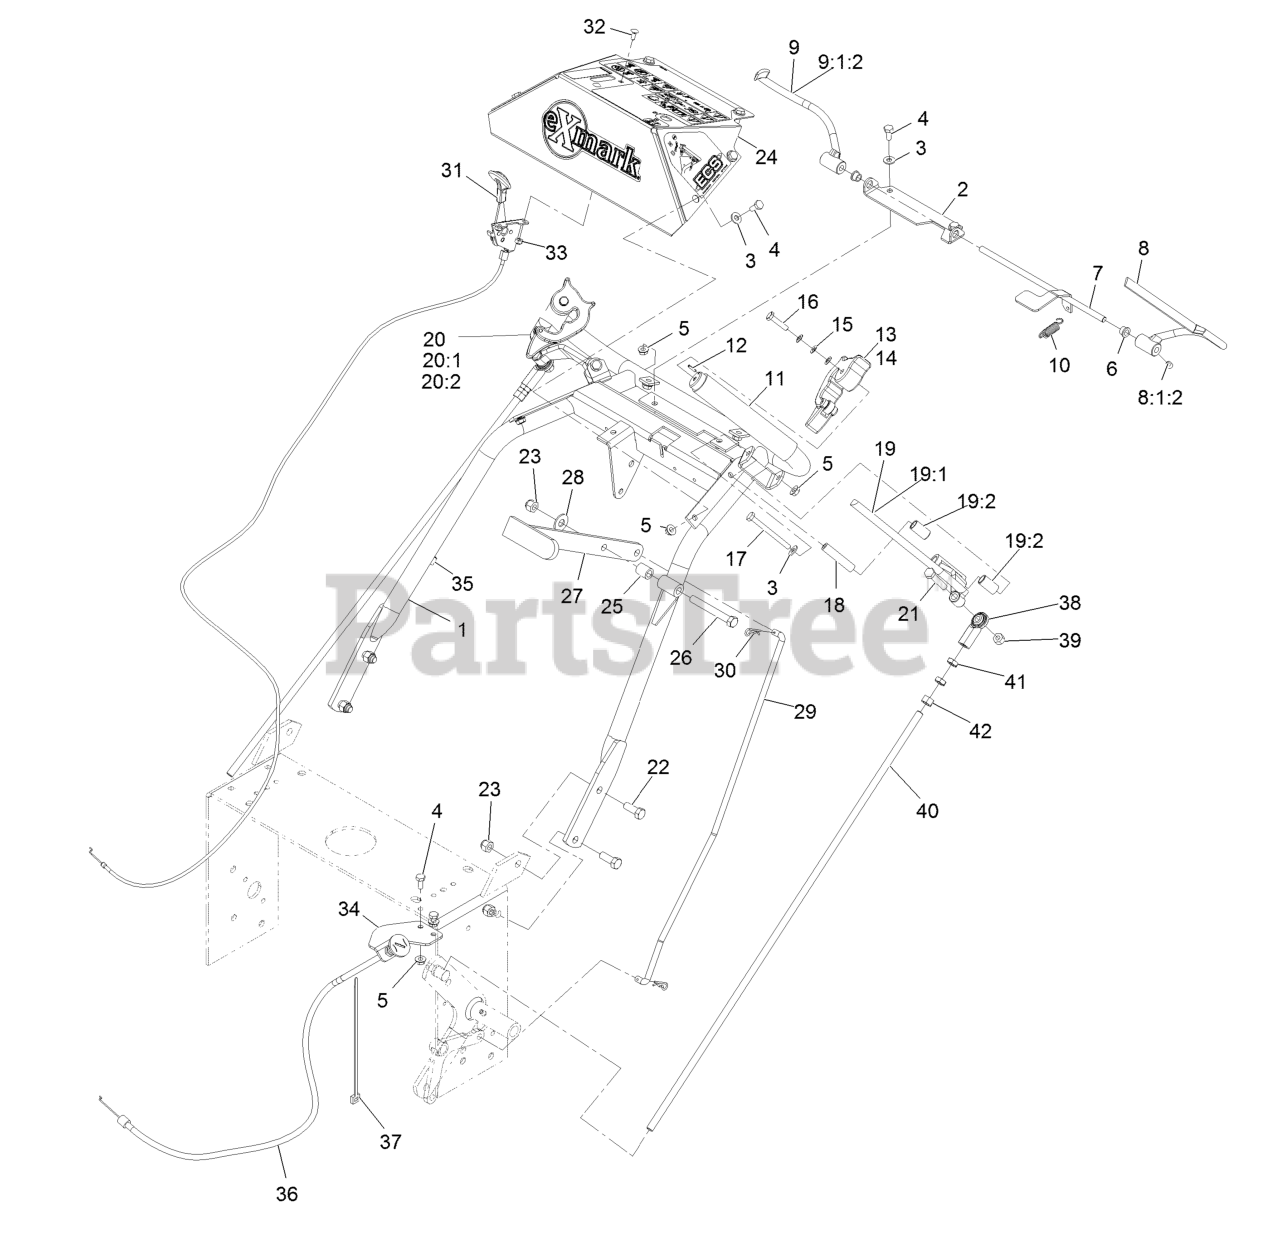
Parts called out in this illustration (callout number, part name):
1	Handle Weldment
2	Bracket, Opc Axle
3	Washer-1/4 SAE
4	Screw-HH 1/4-20 X 5/8
5	Nut-Whizlock 1/4-20
6	Bushing-Nylon
7	Rod Weldment, OPC
8	Wld,LH OPC Lever
8:1:2	Setscrew-5/16-24 X 5/16
9	Wld,RH OPC Lever
9:1:2	Setscrew-5/16-24 X 5/16
10	Spring-Extension
11	Grip-Bar, Handle
12	Pin-Spring
13	Latch, Thumb LH
14	Latch, Thumb RH
15	Washer-Spring Disc 1/4
16	Screw-HH 1/4-20 X 1 1/8 W/Nylon
17	Screw-HH 1/4-20 X 2 3/4
18	Bushing-Lever, Drive
19	Asm, Drive Lever LH
19:1	Wld,LH Drive Lever
19:2	Bushing, Sleeve
20	Asm, Drive Lever RH
20:1	Wld,RH Drive Lever
20:2	Bushing, Sleeve
21	Screw-HH 5/16-18 X 1 3/4
22	Screw-HH 3/8-16 X 1
23	Nut-Nyloc 3/8-16
24	Asm, Console (109-4649-03) W/Decals
26	Screw-HH 3/8-16 X 3
27	Clutch Lever W/Grip
28	Washer-3/8 Std
29	Linkage, Upper
30	Hairpin-Cotter
31	Control, Throttle
32	Bolt-Carriage #10-24 X 1/2
33	Nut-Nyloc #10-24
34	Bracket-Cable, Choke
35	Clip-Cable
36	Cable-Choke
37	Tie-Cable 7 15/16 (Large)
38	Balljoint
39	Nut-Nyloc 5/16-18
40	Linkage, Wheel Drive
41	Nut-Jam 3/8-24
42	Nut-Hex 3/8-24
